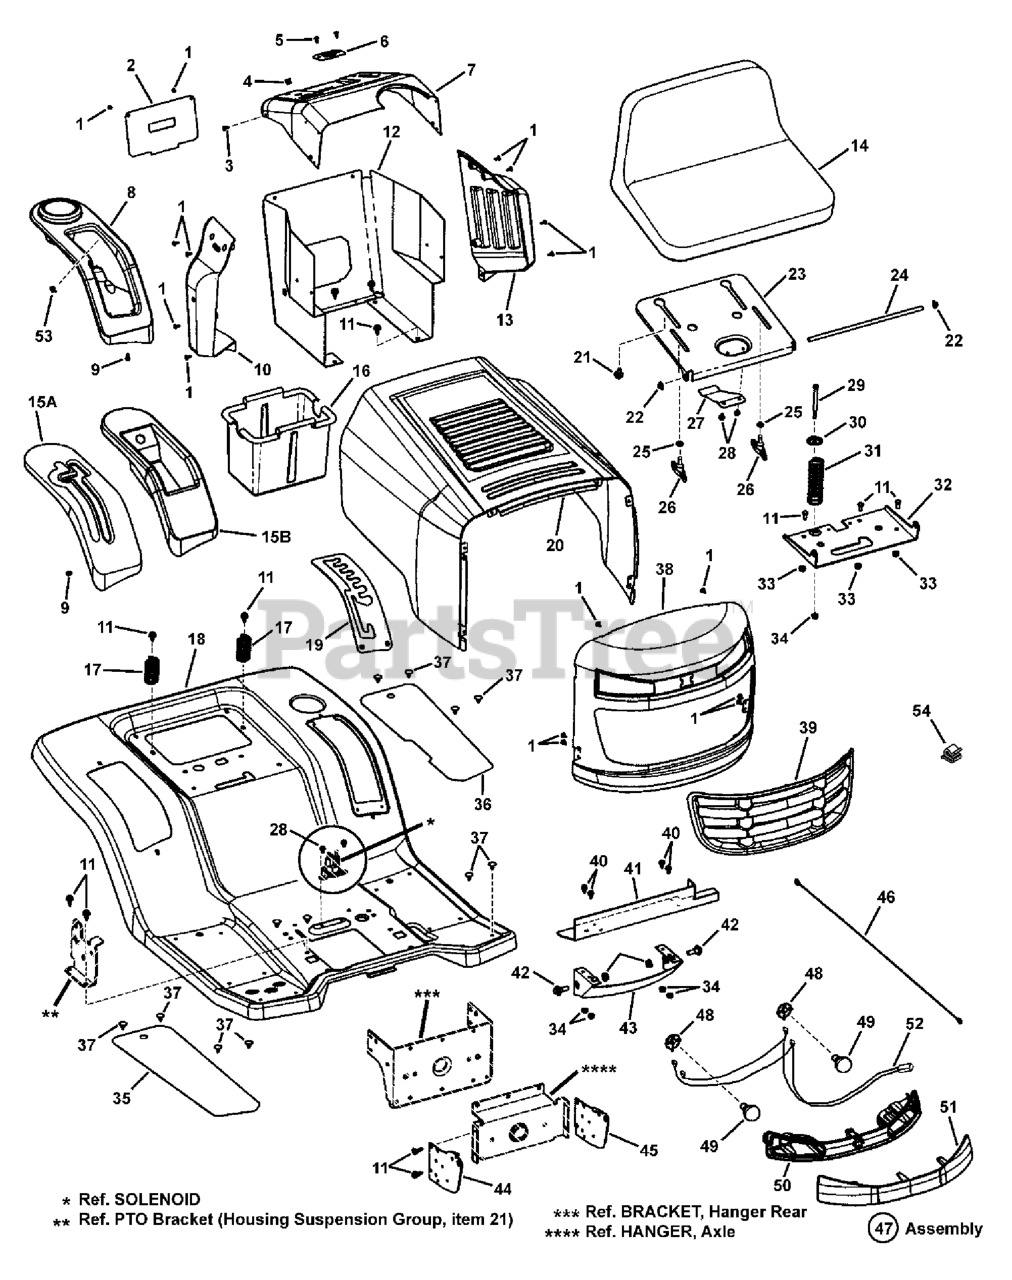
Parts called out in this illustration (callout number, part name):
1	SCREW, THREAD FORMING 10-24X.340MIN THREADS
2	PANEL, ACCESS
3	SCREW, 0.375 X #8 SELF TAP Z/BL CHROMATE
4	BUSHING - INSULATING
5	SCREW, 1/4" ABX.50
6	BEARING, STEERING
7	DASH-TWIN
8	POD W/ CUP HOLDER
9	SCREW, 1/4-20 THREAD CUTTING
10	PANEL, RIGHT SIDE
11	SCREW, 5/16-18
12	SUPPORT, DASH
13	PANEL, LEFT SIDE
14	SEAT, LOW BACK
15A	POD W/ DRIVE
15B	POD W/ COMPARTMENT
16	CONTAINER, BATTERY
17	SPRING, COMPRESSION 2.43LENGTH
18	SEAT DECK
19	PLATE, INDEX
20	HOOD, WM2
21	BOLT, SHOULDER 5/16-18
22	CAP, PUSH ON
23	SUPPORT, SEAT
24	ROD, PIVOT
25	FW, .34X.62X16GA
26	BOLT - WING, 0.62L X 5/16-18 UNC 2A
27	SPRING - LEAF
28	SCREW, 1/4-14X.38"ST-
29	BOLT, SHOULDER 1/4-20 X 3.652 2A
30	WASHER - CUP, 1.50 OD X 0.344 ID
31	SPRING, COMPRESSION 4.57 FREE LENGTH
32	BRACKET, SEAT PIVOT
33	NUT, Nylock 5/16-18
34	NUT, HEX FLANGE 1/4-20
35	MAT, RH
36	MAT, LH
37	FASTENER PANEL
38	HOOD, GRILLE
39	LOUVER, INSERT
40	HHCS, 1/4-20 x 5/8
41	BRACKET, SUPPORT
42	SHOULDER BOLT, 3/8-16X1.06
43	BRACKET, LOWER PIVOT
44	SUPPORT - GRILLE, RIGHT
45	SUPPORT - GRILLE, LEFT
47	ASSY, HEADLIGHT, TCT, MURRAY
48	SOCKET, LIGHT
49	BULB, 12.8V
50	HOUSING, LIGHT
51	LENS, LIGHT
52	HARNESS-HEADLIGHT
53	CUTTING HEIGHT INDICATOR
54	RETAINERS, S-Clips
